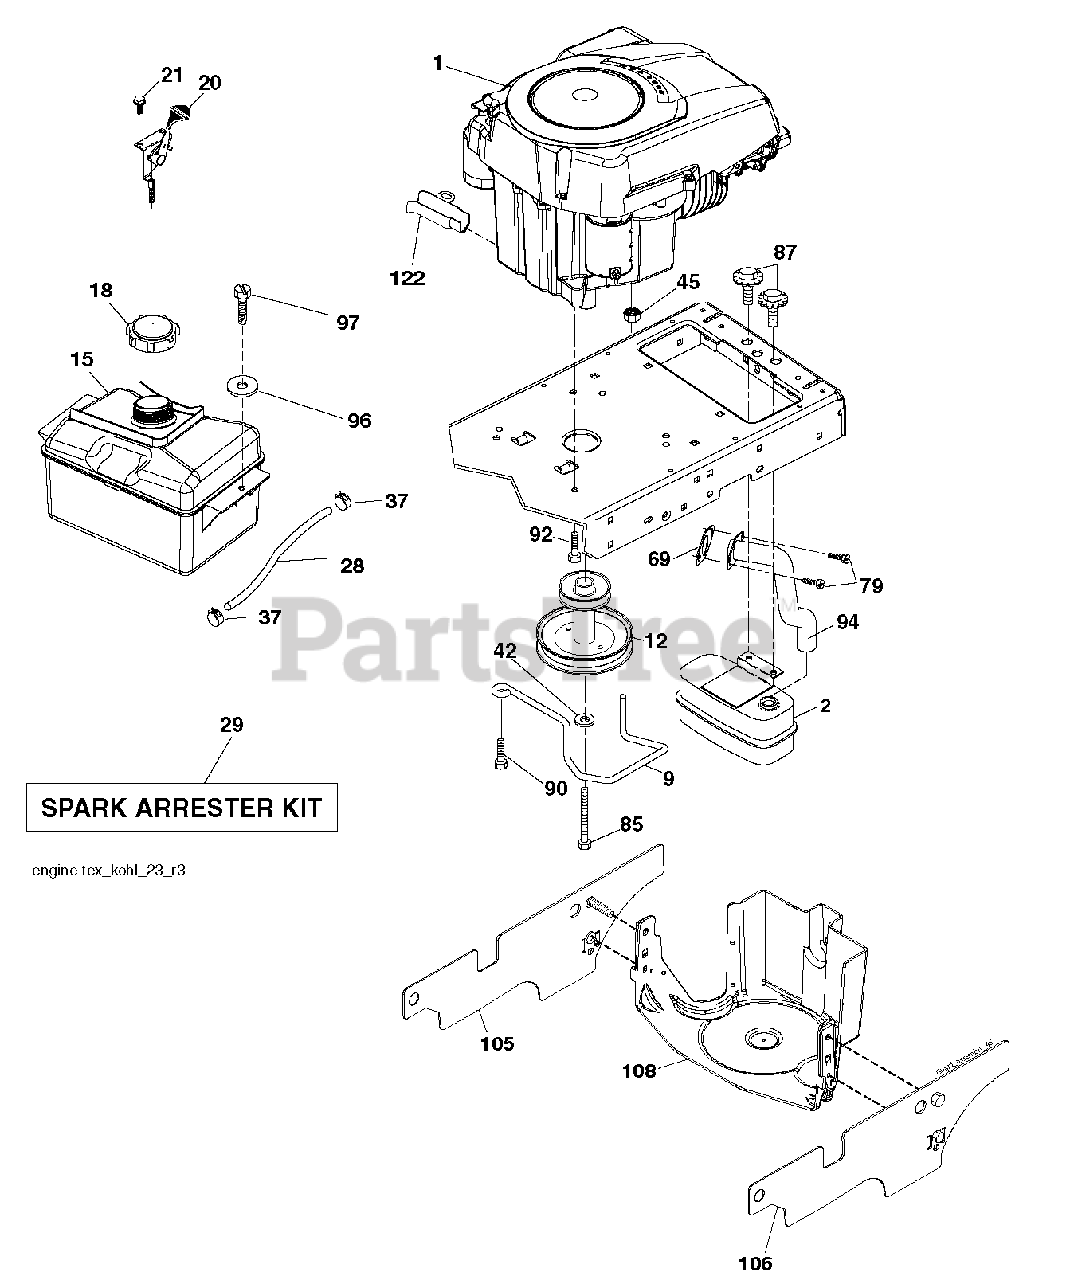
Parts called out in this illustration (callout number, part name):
2	MUFFLER.SINGLE.CYL.KOHL/B&S
9	KEEPER.BELT.ENGINE.3.25 (3 2)
12	PULLEY ENGINE
15	RP TANK FUEL FRT 1.5 GAL
18	CAP ASM.FUEL.2.25"FR.
20	CONTROL.TH/CK.C.
21	SCREW.#10 X 0.750.BOS
28	LINE.FUEL.20
29	KIT.SPARK ARRESTOR 794945 B&S
37	HOSE CLAMP
42	LOCKWASHER
45	NUT
69	GASKET.EXHAUST.KOHLER
79	SCREW.SOCKET HD.5/16-1
85	BOLT HEX 7/16-20X4-1/4"
87	BOLT, 5/16-18 X 1 3/4
90	SCREW 3/8-16X1
92	SCREW 3/8-16X1
94	RP.TUBE.EXHAUST.KOHL.COURAGE
97	SCREW HEXWSHR 1/4-20X3/4
108	ENGINE COVER
122	EXTENSION DRAIN OIL
